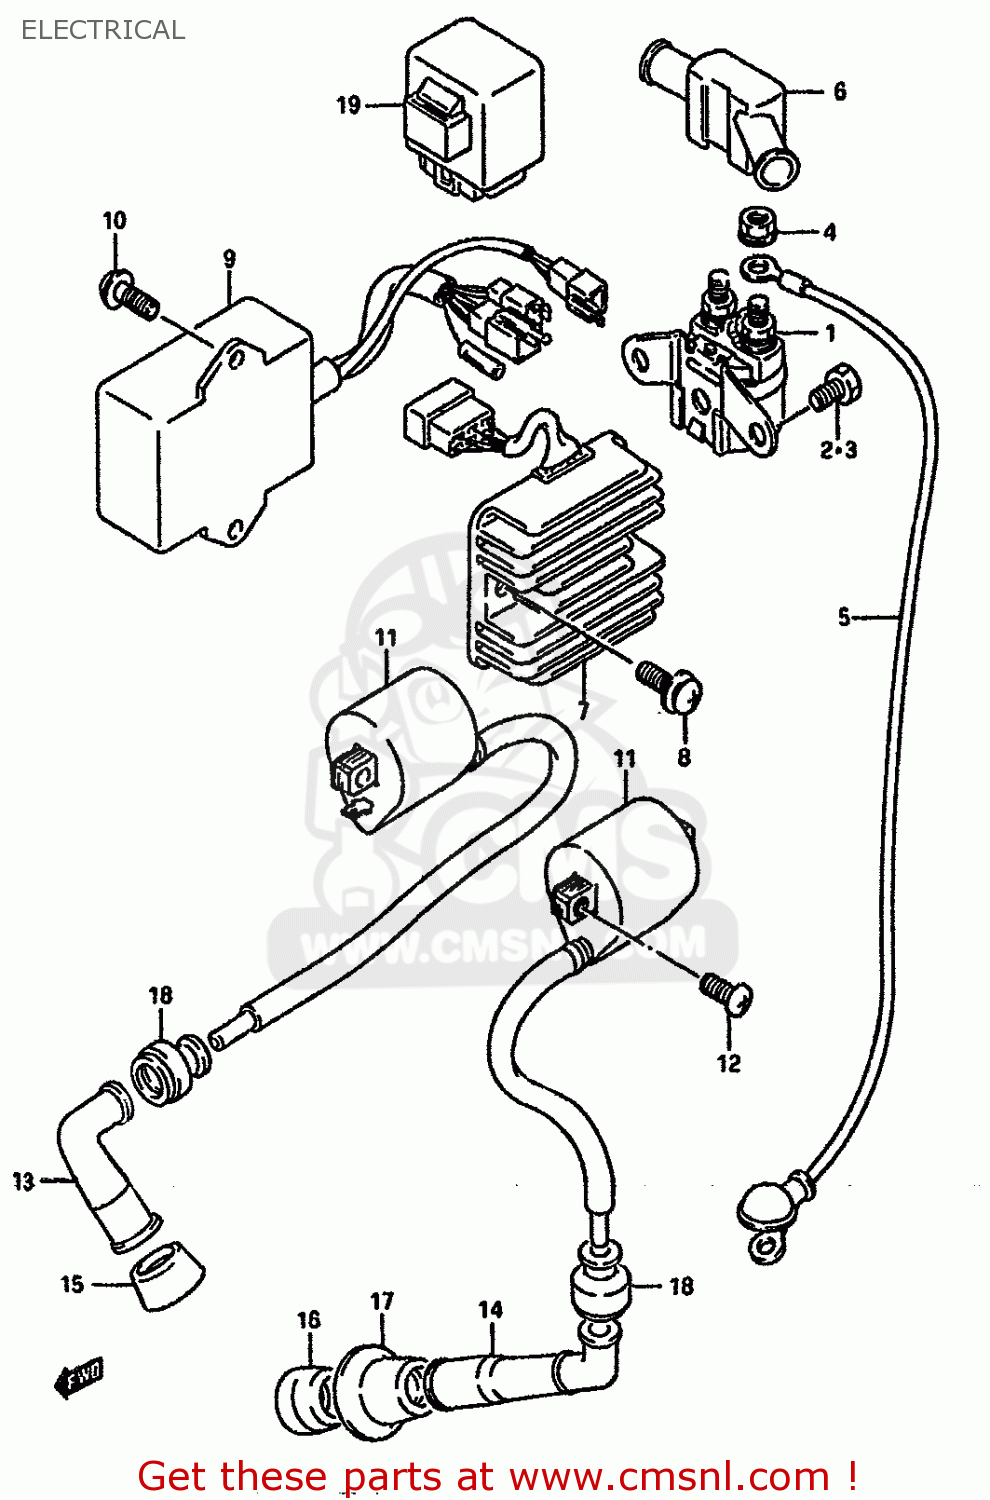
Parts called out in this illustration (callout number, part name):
1	RELAY ASSY,STARTING MOTOR
2	SCREW(6X8)
3	BOLT
4	NUT
5	WIRE,STARTING MOTOR
6	CAP,STARTER RELAY
7	RECTIFIER ASSY
8	SCREW
9	CDI UNIT
10	SCREW
11	COIL ASSY,IGNITION
12	SCREW
13	CAP,SPARK PLUG
14	CAP,SPARK PLUG
15	SEAL,SPARK PLUG CAP
16	SEAL,SPARK PLUG
17	COVER,SPARK PLUG CAP,L
18	SEAL,HIGH TENSION CORD
19	CONTROL UNIT,DECOMP
